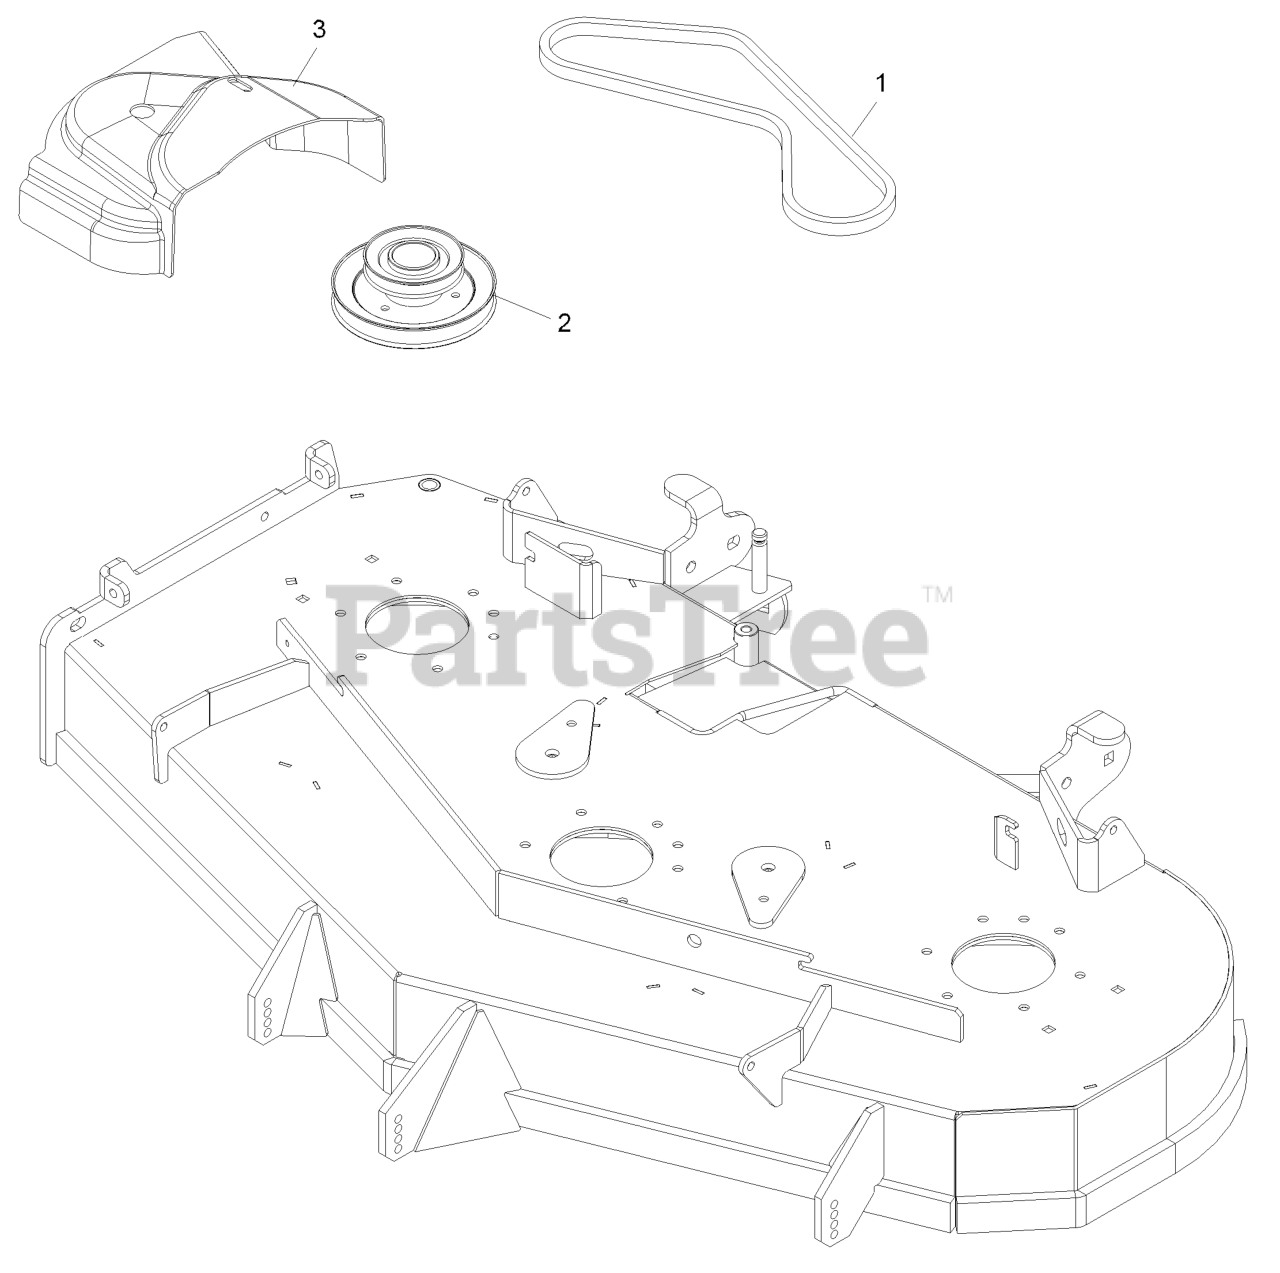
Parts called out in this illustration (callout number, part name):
1	BELT, BLOWER 52"DECK
2	JACKSHAFT,UV DRIVE 524
3	COVER,BELT UV 52
